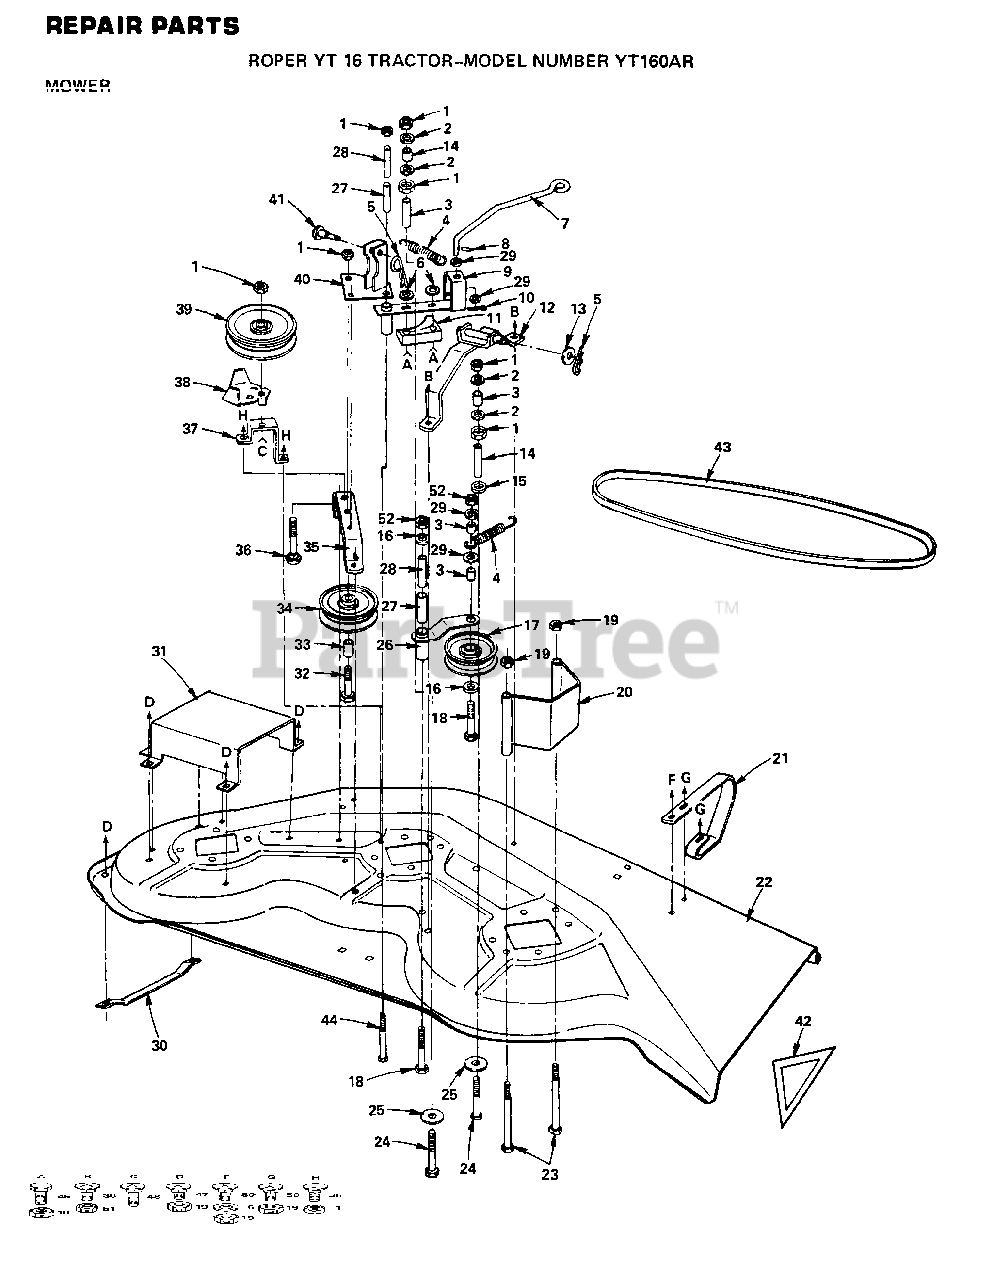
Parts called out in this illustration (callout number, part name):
2	WASHER
3	SPLIT SPACER YTV
4	SPRING T
6	WASHER
7	ROD BRAKE LTV
9	ARM ASY BRAKE Y
11	BRAKE-BLOCK YTV
12	ASSY RH LIFT YTV
14	SPACER BRAKE LTV
16	WASHER
17	IDLER.FLAT.GTV
18	BOLT
20	ASSY RH BELT GRD
23	BOLT
25	WASHER
27	"LINER YTV, BEAR."
28	BRNG-SLEEVE YTV
29	WASHER
30	RUNNER-LH M
31	GUARD-LH YTV
32	BOLT - HEX 3/8 - 16 X 3
33	SPACER-SPLIT YTV
34	IDLER-FLAT YTV
35	BRACKET IDLER YTV
36	BOLT
38	GUARD-IDLER YTV
39	IDLER-INSIDE T
44	BOLT
46	BOLT
47	BOLT
50	BOLT
51	LOCKNUT
52	LOCKNUT
